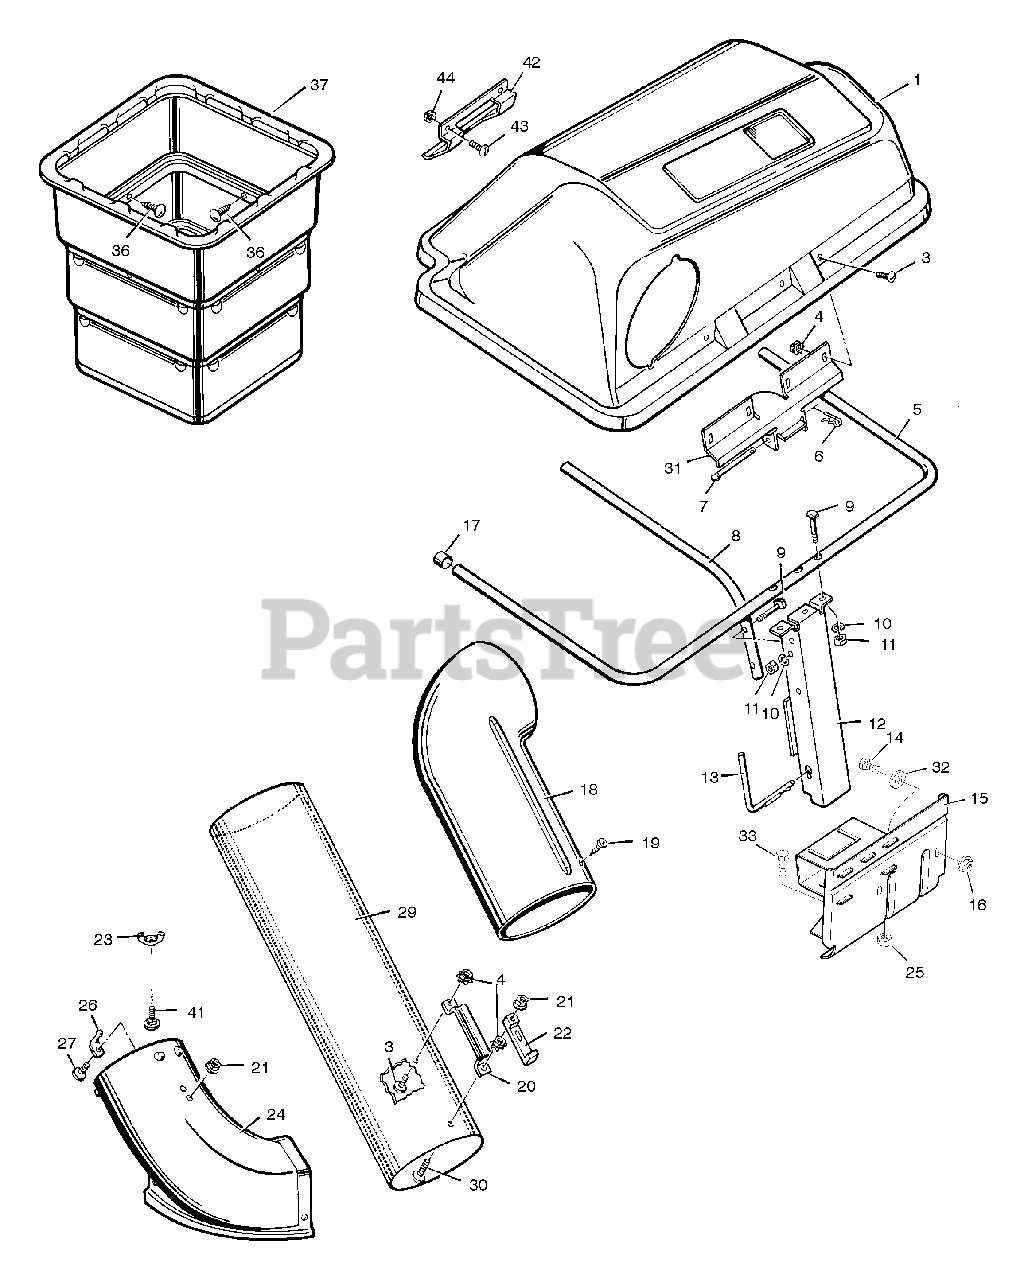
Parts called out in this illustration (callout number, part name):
1	Cover
4	Locknut
5	Tube, "U"
6	Pin, Hair
7	Pin, Hinge
8	Tube, Center
9	Bolt, Special
10	Lockwasher
11	Nut, Hex
12	Channel Assembly
13	Pin, Channel
14	Bolt, Hex
15	Mount Assembly, Bagger
16	Nut, Hex
17	Cap, End
18	Elbow
20	Handle, Connector Tube
21	Locknut, Flange
22	Latch, Rubber
23	Wingnut
24	Tube, Extension
25	Hex Nut
26	Pin, Latch
27	Bolt, Carriage
29	Tube, Connector
31	Hinge, Cover
33	Bolt, Hex
36	Fastener, Plastic
37	Containers (Quantity 2)
41	Bolt, Carriage
42	Handle, Plastic
44	Nut, Hex
